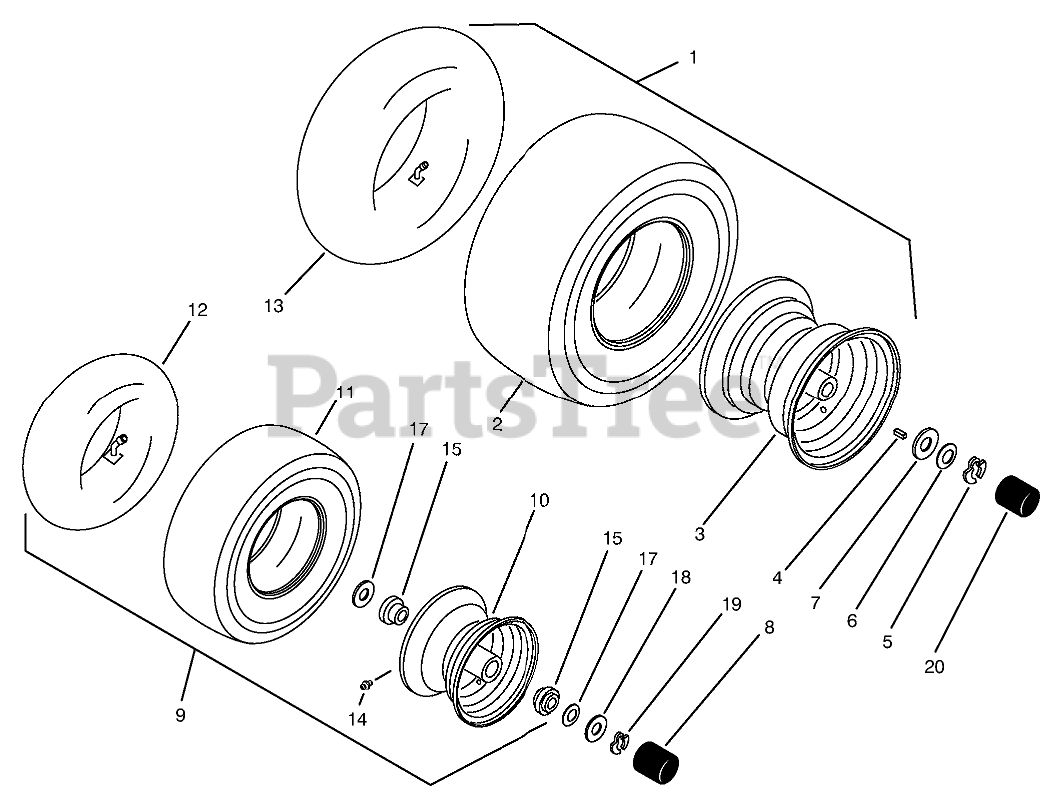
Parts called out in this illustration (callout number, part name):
4	KEY-SQUARE
5	RING-RETAINING
7	WASHER
13	TUBE-TIRE
14	ZERK-GREASE
15	BEARING-WHEEL
17	WASHER-SHIM
18	WASHER-WHEEL
20	HUBCAP
